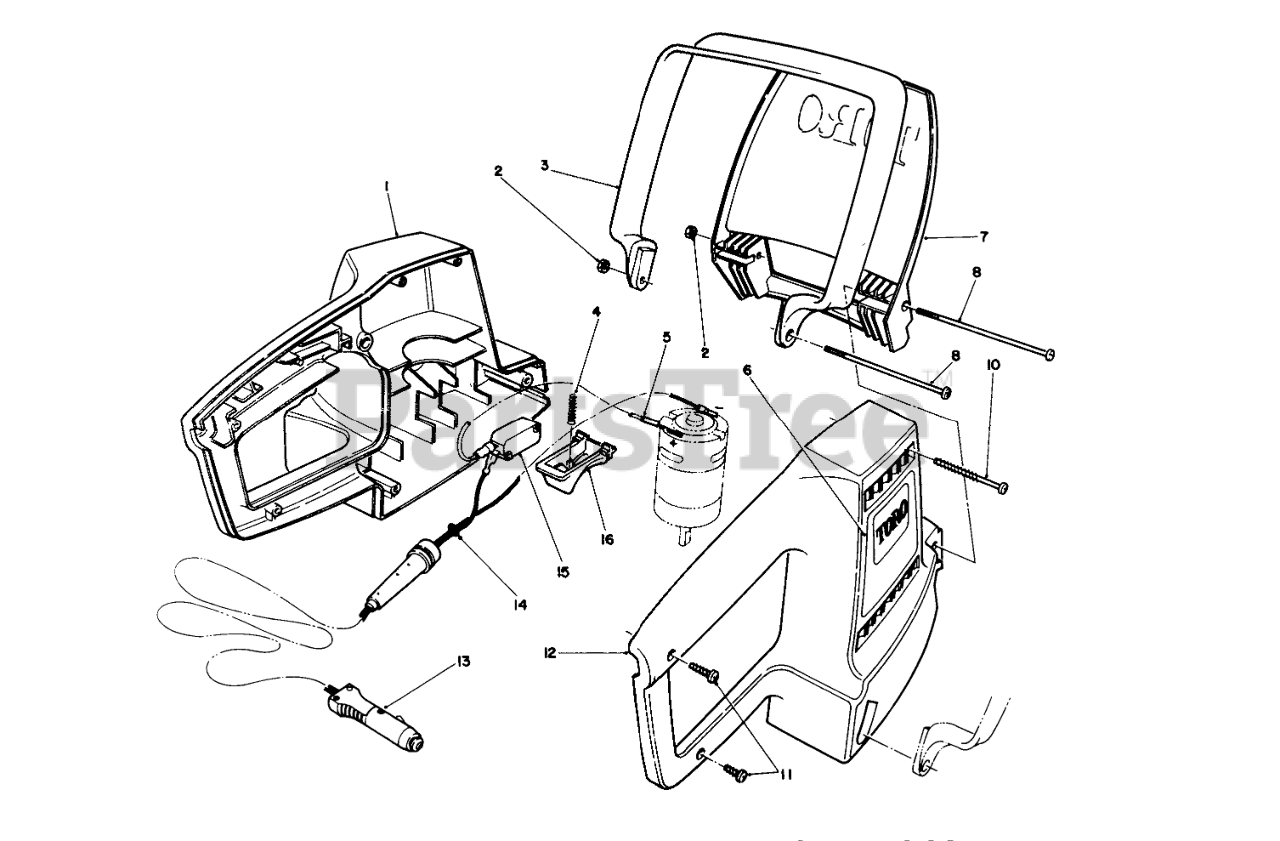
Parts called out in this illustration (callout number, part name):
1	Housing-Handle, L.H.
2	NUT-HJ
3	ASSIST HANDLE
4	SPRING-TRIGGER
5	WIRE ASSEMBLY
6	DECAL-HEDGE, RT
7	SHIELD
8	SCREW-PPH
10	SCREW - #8 X 2.0
11	SCREW-PPH
12	Housing-Handle, R.H.
13	CORD-HEDGE
14	Relief-Strain
15	SWITCH
16	TRIGGER
